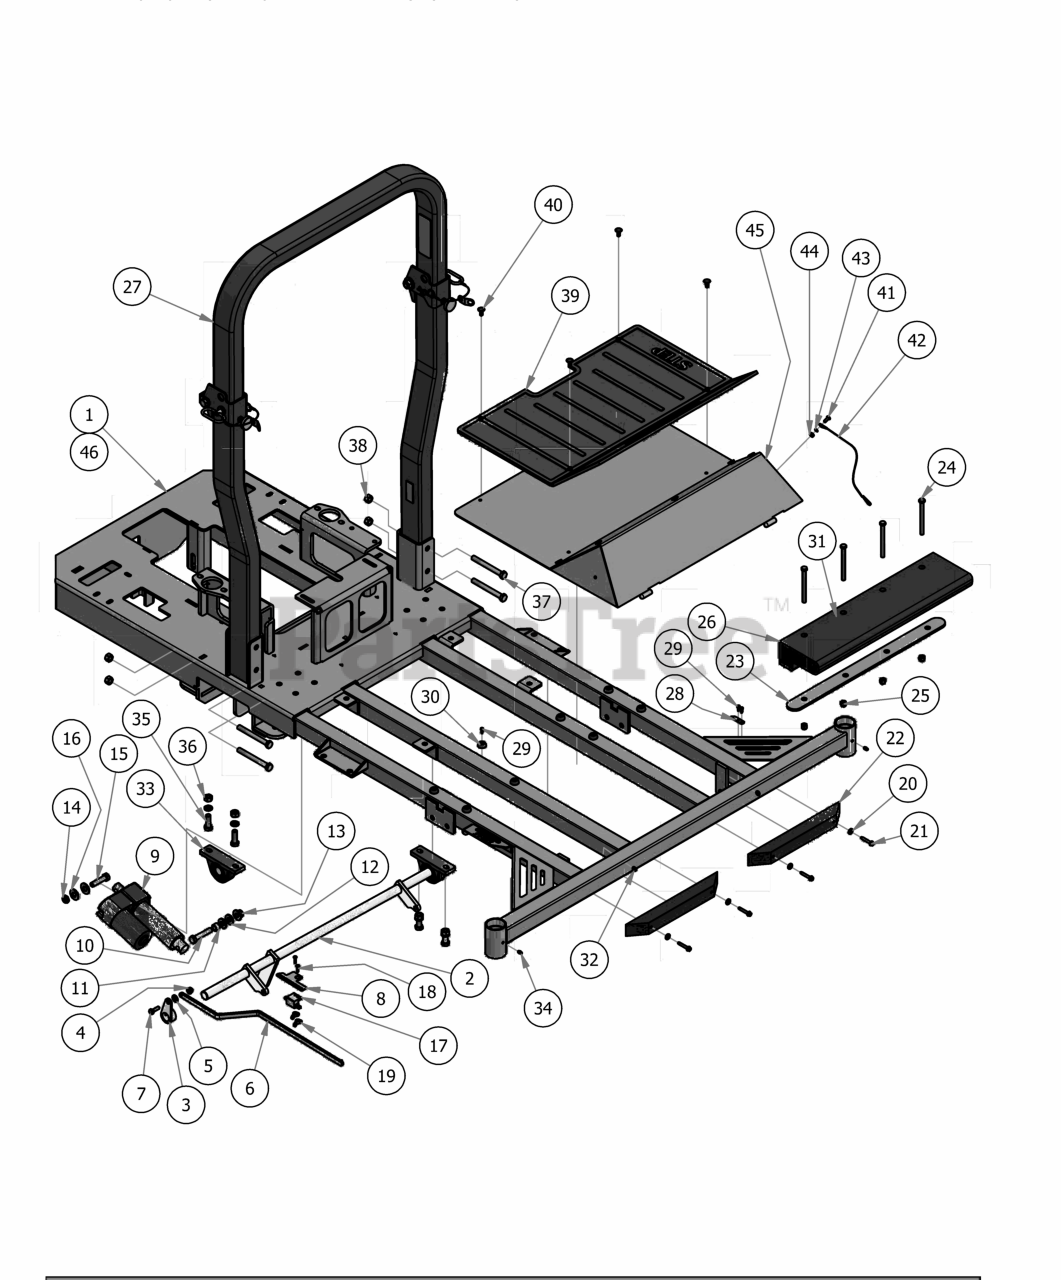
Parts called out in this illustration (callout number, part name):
1	Diesel 4cyl 72" Frame
2	Actuator Bar
3	Height Indicator Lever
4	5/16" Flange Nut
5	.360 ID Plastic Washer
6	Height Indicator Bar
7	5/16" x 1" Bolt
8	Deck Stop Bracket 2008
10	1/2" x 2 1/2" Hex Bolt
11	1/2 x 1/2 Spacer
12	.505 Nylon Spacer
13	1/2-13 Nylon Flange Nut-Orange
14	1/2" Nylock Nut (1/2 Jam)
15	1/2" x 2" Hex Bolt
16	1/2" Washer (Grade 8)
17	Deck Stop Switch
18	1024 x 1" Allenhead Bolt
19	10-24 Wing Nut
20	1/4" Flat Washer
21	1/4" x 1 1/2" Self Tapping Screw
22	14" Rubber Bumper
23	Diesel Weight Bar Bracket
24	3/8" x 4 1/2" Bolt
25	3/8 Nylock Nut
26	58lb Diesel Weight
27	2014 & Newer Diesel 2x3 Folding ROPS
28	2006 Floor Panel Stop
29	#10 x 1/2" Self Tapping Screw
30	Button Bumper
31	1/4 x 1 Hex Head tek screw
32	Brass Washer for Weld-On Hinge
33	pillow block 2bolt sealmaster
34	1/4" Press in Grease Fitting
35	1/2" x 1 1/2" Hex Bolt
36	1/2" Hex Nut
37	1/2" x 4 1/2" Bolt
38	1/2" Center Lock Nut
39	AOS Floor Mat
40	5/8" Christmas Tree Fastener
41	1/4" x 5/8" Buttonhead Bolt
42	Floor board Cable W/ Swivel Ends
43	1/4" Lock Washer
44	1/4" Hex Nut
45	Floor Panel
46	Diesel 4cyl 61" Frame Suspension
